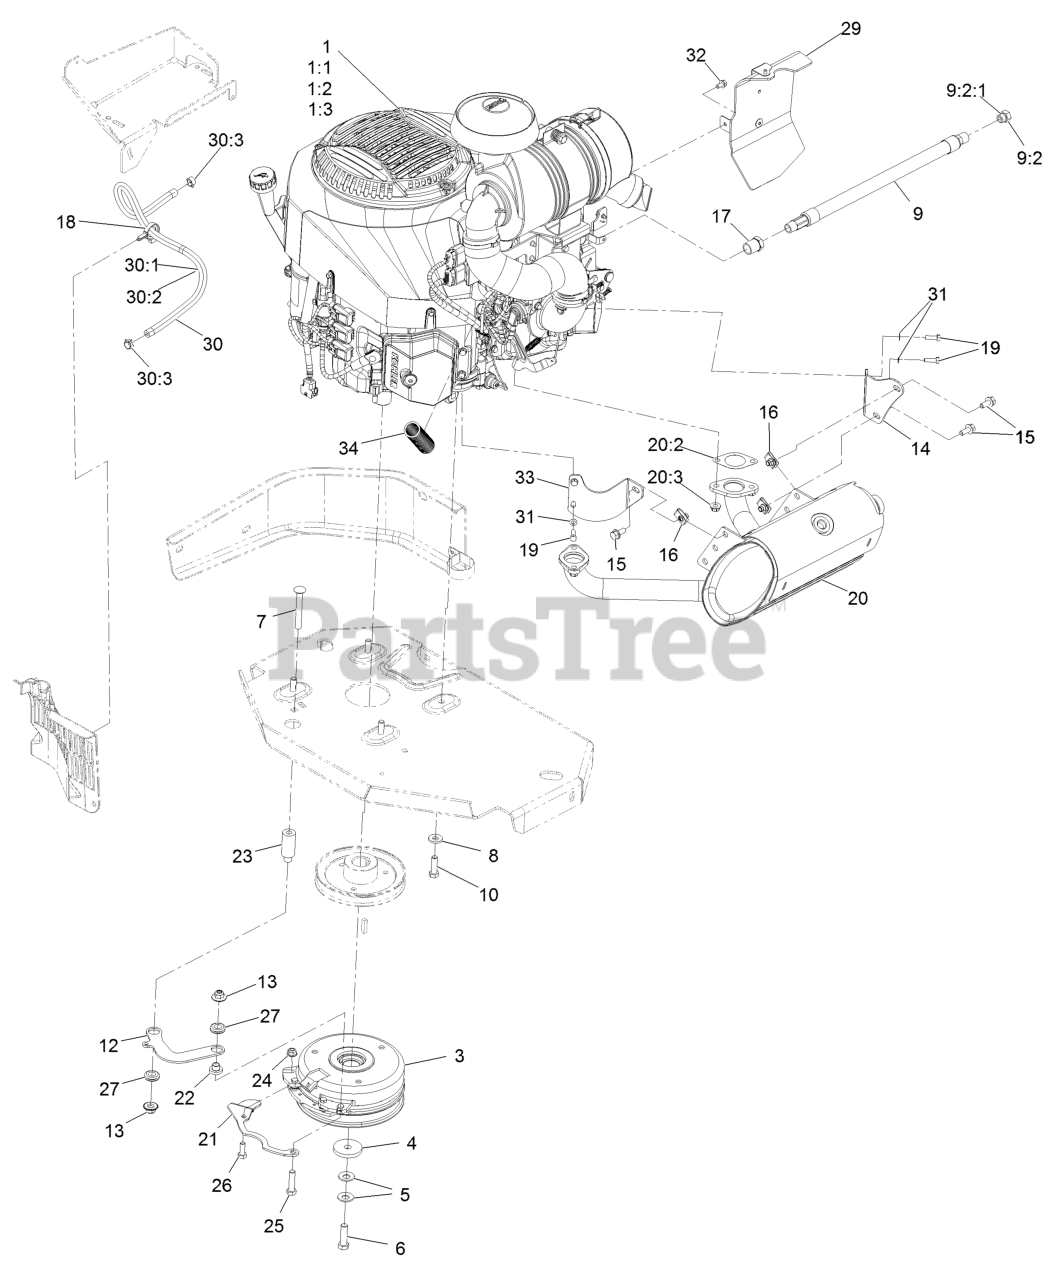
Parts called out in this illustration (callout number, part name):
1:1	Kohler 52 050 02-S Engine Oil Filter
1:2	Kohler 25 083 01-S Engine Air Filter
1:3	Kohler 25 083 04-S Safety Filter
3	CLUTCH KIT
4	WASHER-CLUTCH
5	WASHER-SPRING
6	SCREW-HH 7/16-20 X 1 1/2 W/LOCTITE
7	SCREW-CARR
8	WASHER-BELLEVILLE
9	OIL DRAIN HOSE ASM
9:2	PLUG-HH
9:2:1	O-RING
10	SCREW-HH
12	LINK-ANCHOR, CLUTCH
13	Nut-Nyloc 3/8-16 Flg
14	BRACKET-MUFFLER
15	SCREW-HHF
17	BUSHING
18	CLAMP-HOSE
19	SCREW-HH M6-1 X 20Mm W/Patch
20	MUFFLER-940-980 KOH EFI
20	MUFFLER KIT
20:2	GASKET-EXHAUST
20:3	NUT-FLANGE, LOCK
21	BELT-GUIDE
24	NUT-HF, NI
25	SCREW-HH
26	SCREW-HH
27	GROMMET-RUBBER
29	REAR BAFFLE ASM
30	FUEL LINE ASM
30:1	HOSE-FUEL
30:2	SLEEVE, THERMAL
30:3	CLAMP-HOSE
31	WASHER-SPRING
32	SCREW-HWH
33	BRACKET-MUFFLER, FRONT
34	CONDUIT-CONVOLUTED
